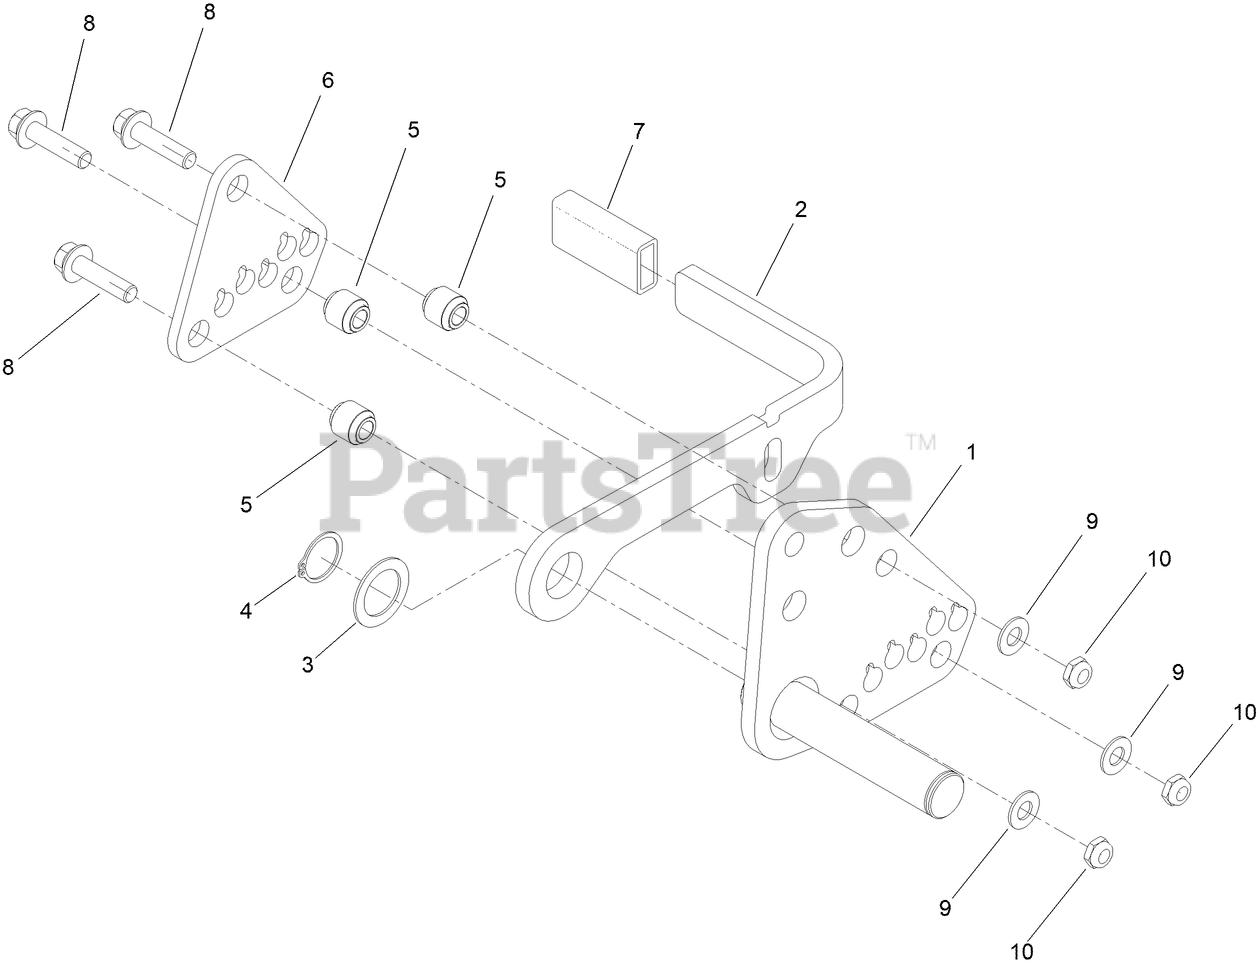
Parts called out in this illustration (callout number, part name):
1	PIVOT ASM-RH HOC
2	LEVER-RAKE, DECK
3	WASHER-THRUST
4	RING-RETAINING
5	SPACER-DOUBLE STEP
6	PLATE-RAKE ADJ, OUTER
7	GRIP-FLAT
8	SCREW-HHF
9	WASHER-PLAIN
